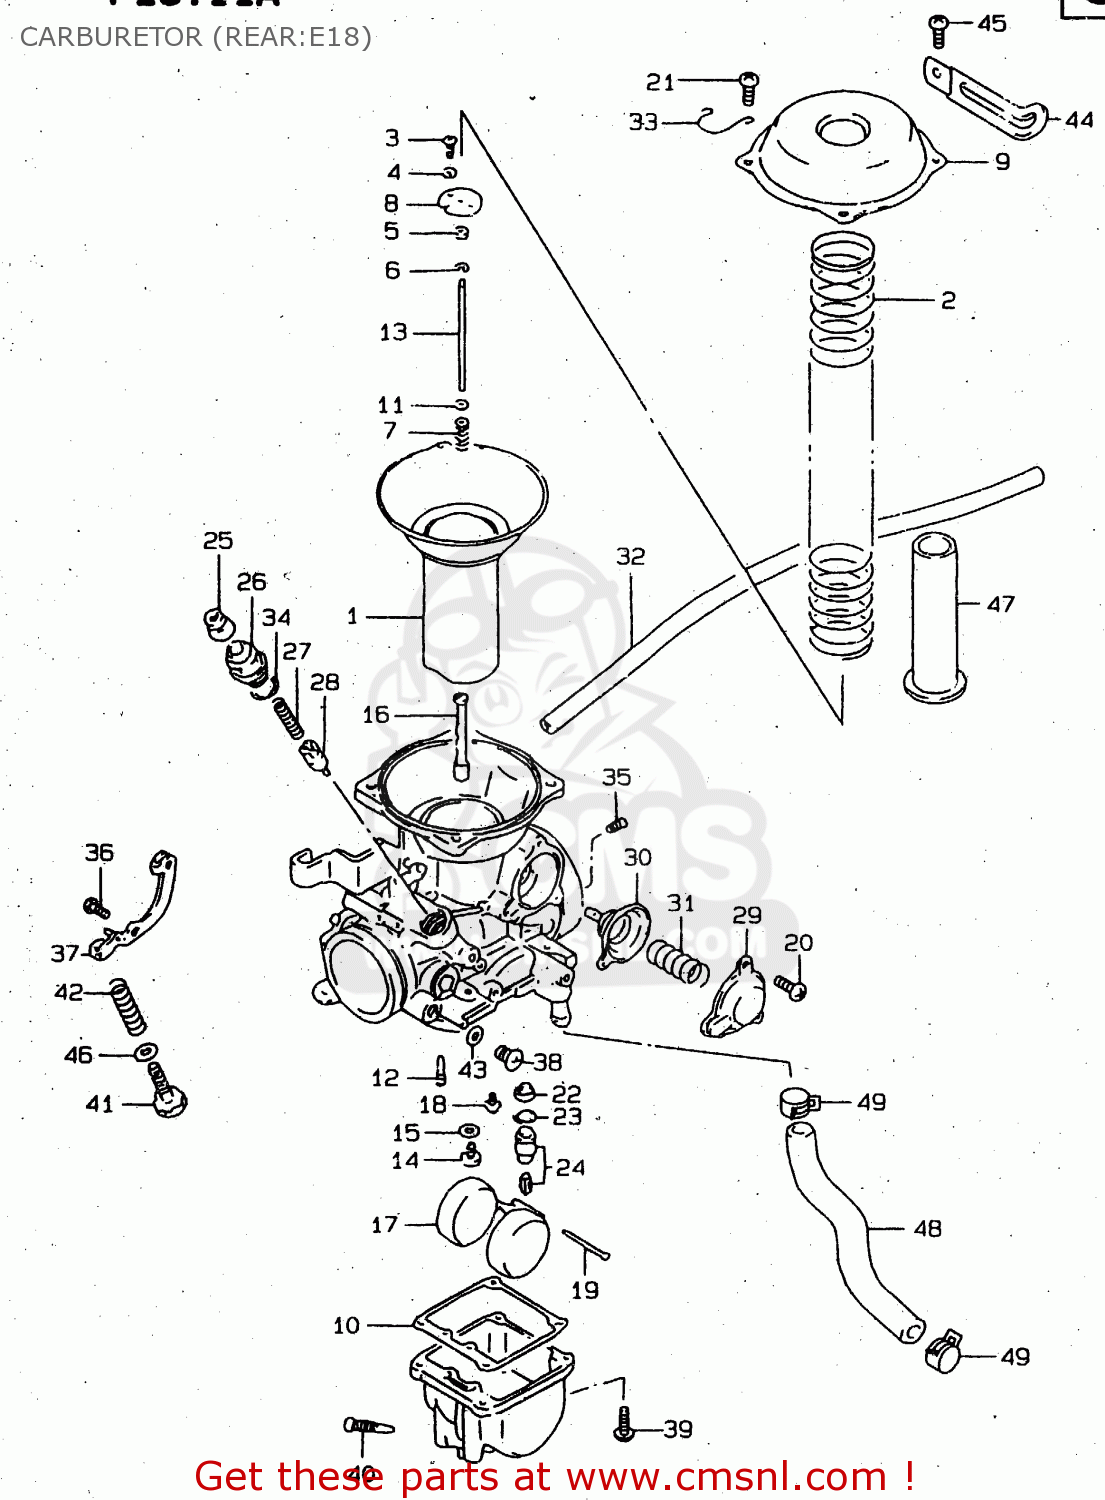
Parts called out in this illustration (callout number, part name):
1	DIAPHRAGM ASSY
2	SPRING,DIAPHRAGM
3	SCREW
4	WASHER,LOCK
5	RING
6	CLIP
7	SPRING
8	PLATE
9	COVER,DIAPHRAGM
10	GASKET,FLOAT CHAMBER (NAS)
11	WASHER
12	JET,PILOT(42.5)
13	NEEDLE (5F107-3)
14	JET,MAIN(107.5)
15	WASHER
16	JET, NEEDLE (P-5)
17	FLOAT
18	SCREW
19	PIN,FLOAT
20	SCREW
21	SCREW
22	FILTER
23	O-RING,NEEDLE VALVE
24	VALVE ASSY,NEEDLE
25	CAP
26	HOLDER,GUIDE
27	SPRING
28	PLUNGER,STARTER
29	COVER
30	DIAPHRAGM ASSY
31	SPRING
32	HOSE(5X8.2X600)
33	CLIP
34	O RING
35	JET,PILOT
36	SCREW
37	LEVER ASSEMBLY
38	SCREW
39	SCREW
40	SCREW,DRAIN
41	ADJUSTER
42	SPRING
43	GASKET,DRAIN PLUG (NAS)
44	CLAMP(L:80)
45	SCREW
46	WASHER
47	RING
48	HOSE,FUEL PUMP & CARBURETOR
49	CLIP
